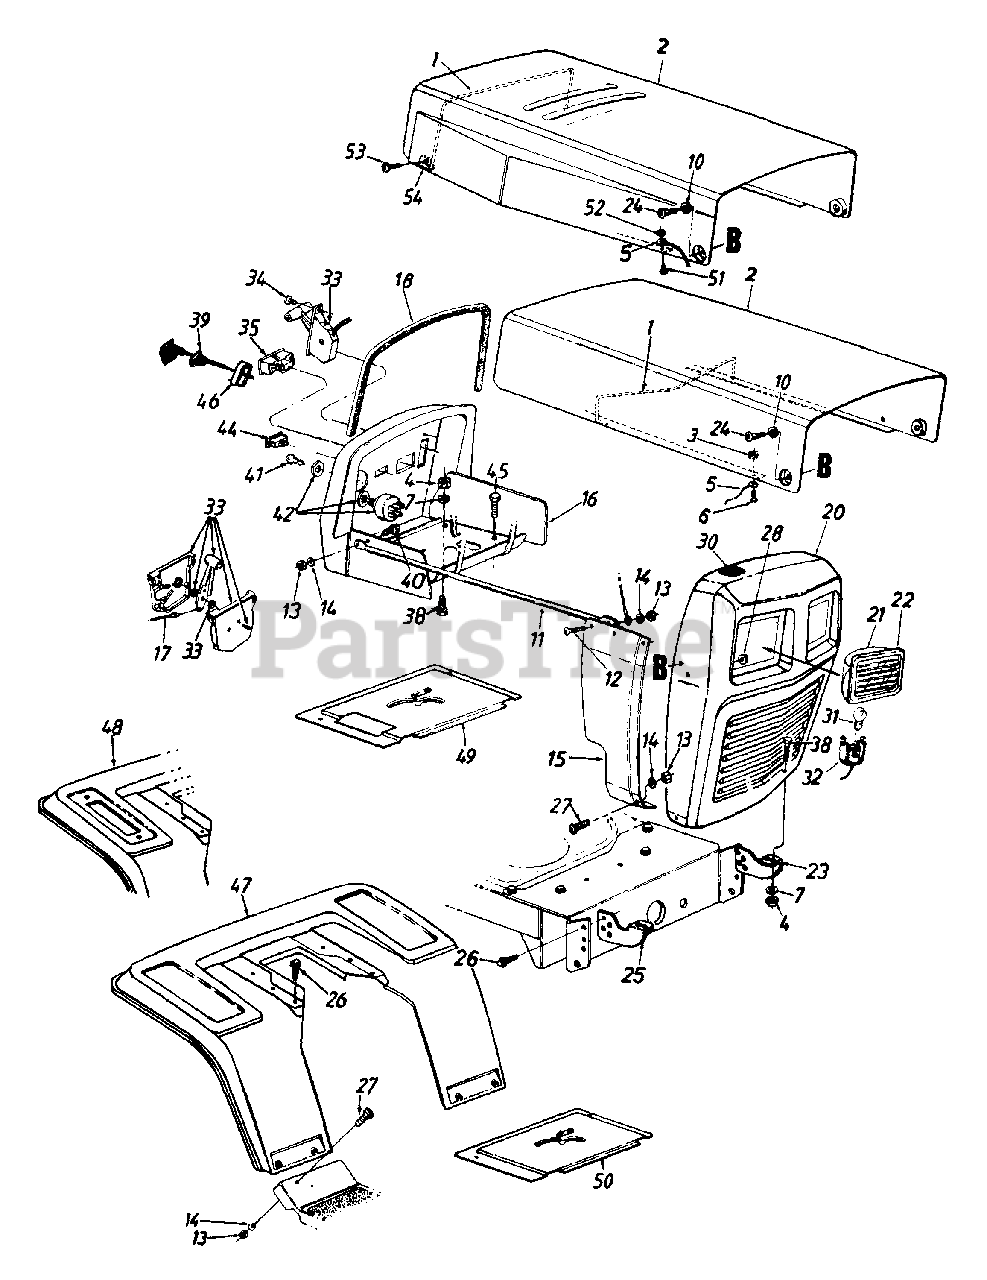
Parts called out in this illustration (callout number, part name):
1	Hood Spring
4	Hex Nut 5/16-18 Thd.
5	Hood Stop 7" Lg.
6	Truss Hd. Scr. #10-24 x 1/2"
7	L-Wash. 5/16" I.D.
10	Washer, 39" I.D. x .62" O.D.
11	Grille Support Rod
12	Truss Hd. Scr. 1/4-20 x .75"
13	Hex Nut 1/4-20 Thd."
14	L-Wash. 1/4" I.D.
18	Molding Strip 31" Lg.
22	Headlight Lens
25	Mounting Brkt. - R.H.
26	Hex Wash. Hd. AB-Tap Scr. 5/16 x .75" Lg.
27	Carriage Bolt 1/4-20 x 2.0" Lg.
28	L-Nut 1/4-28 Thd.
30	Foam Strip 3/8 x 1-1/8 x 1-1/2
31	Bulb
32	Twist Lock Lamp Socket
33	Throttle Box Ass'y.
34	Truss Mach. AB-Tap Scr. #10 x .5" Lg.
35	Ammeter
38	Hex Bolt 5/16-18 x .75" Lg.
39	Choke Control 29" Lg.
40	Hex Bolt 1/4-20 x .62" Lg.
41	Ignition Key
42	Ignition Switch
44	Light Switch
45	Hex Wash. Hd. B-Tap Scr. 5/16-18 x .5" Lg.
46	Choke Retainer
49	Shift Cover w/ Cutout
50	Shift Cover
51	Pop Rivet
52	Fl-Wash. .203" I.D. x .41" O.D.
53	Oval Hd. Self-Tap Scr. 1/2" Lg.
54	Hood Spring Retainer
